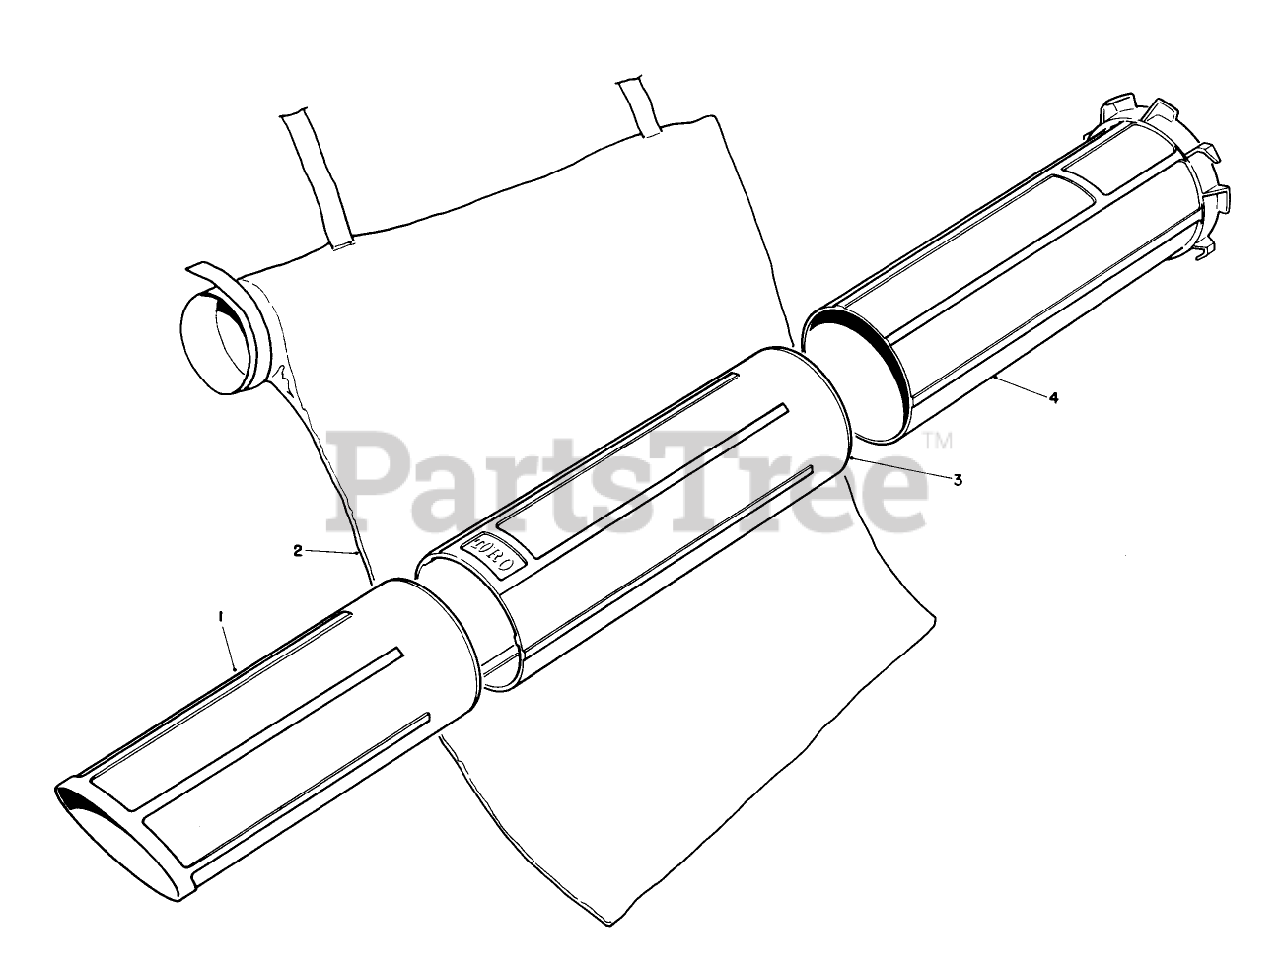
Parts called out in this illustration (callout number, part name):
1	LOWER VAC TUBE
2	VACUUM BAG
3	MIDDLE VAC TUBE
4	Tube-Vacuum, Upper
